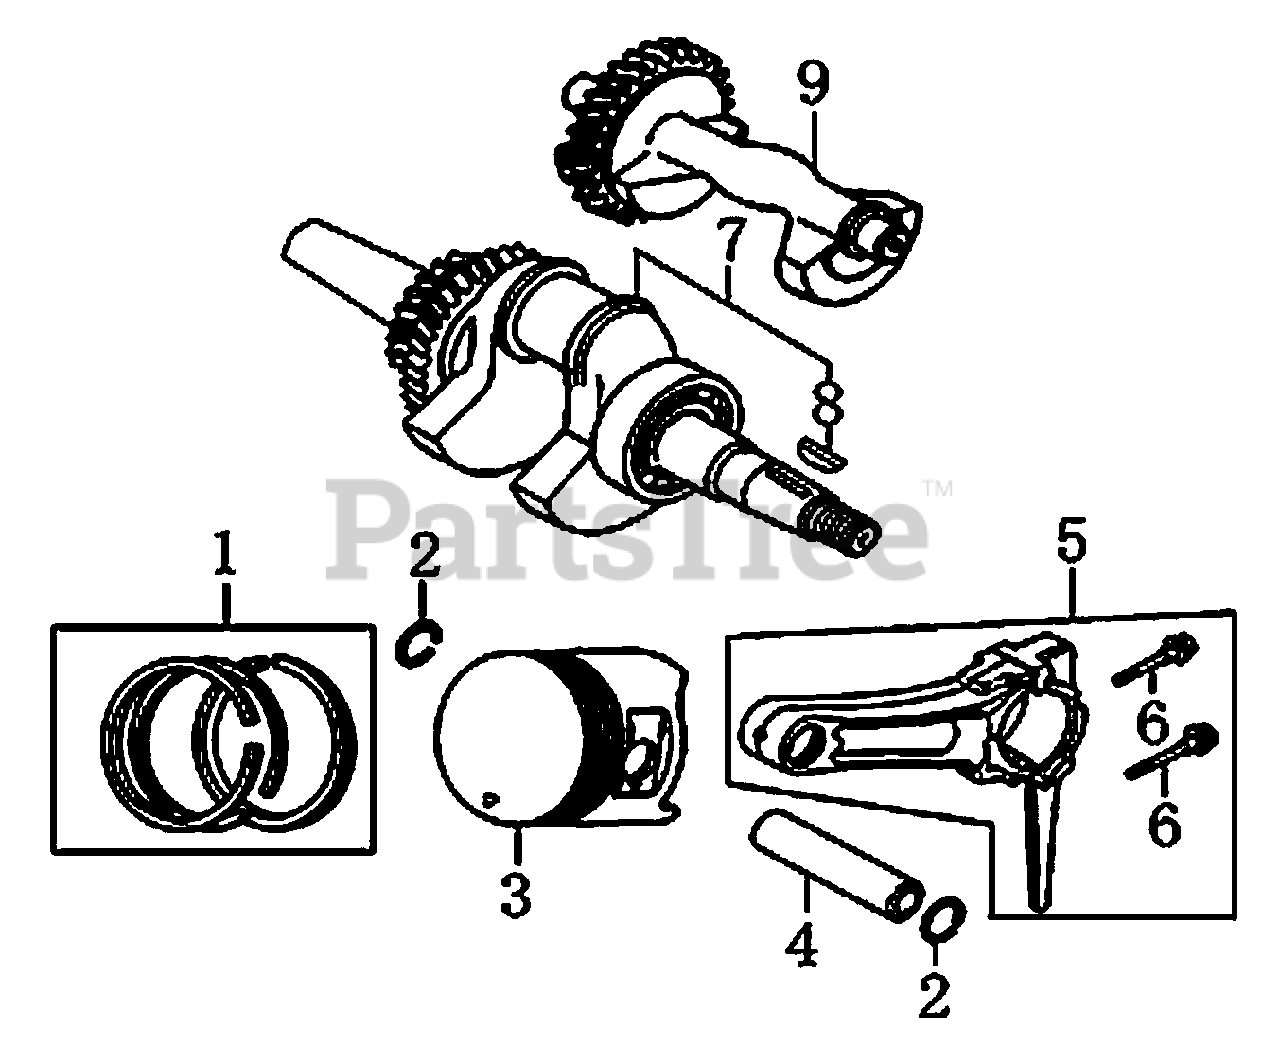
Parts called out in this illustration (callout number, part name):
1	RING SET,PISTON
2	CLIP,PISTON PIN
4	PIN,PISTON
5	CONNECTING ROD ASSY
6	BOLT,CONNECTING ROD
7	CRANKSHAFT ASSY
8	KEY,SPECIAL WOODRUFF
9	WEIGHT,BALANCER
